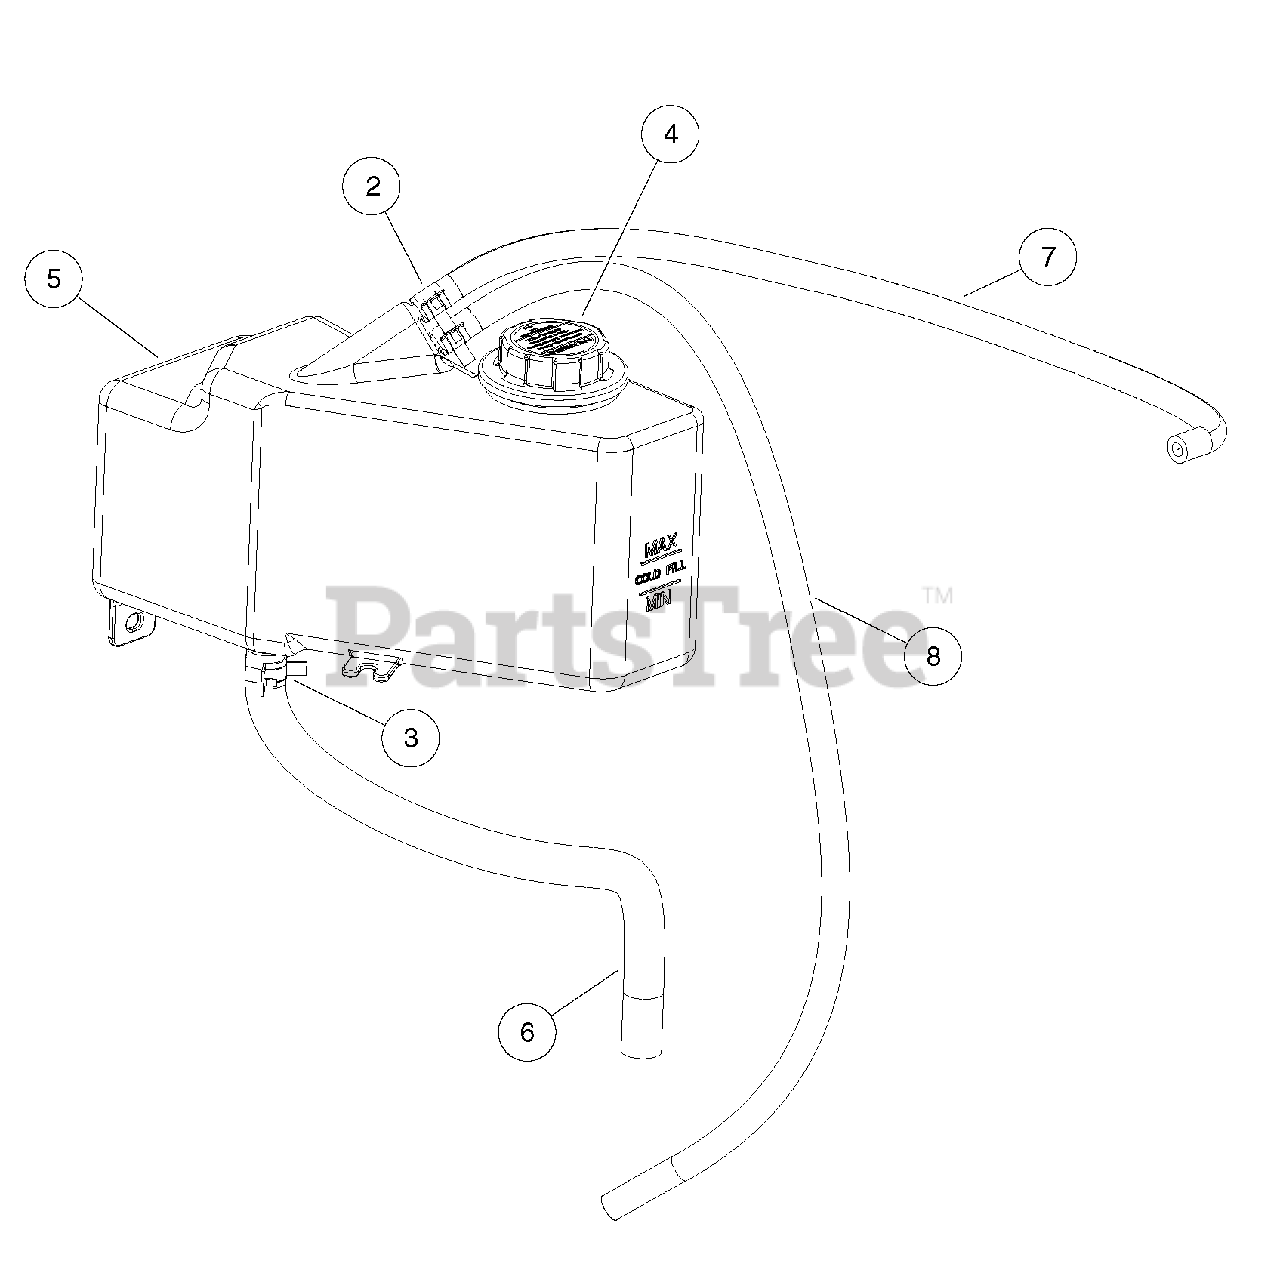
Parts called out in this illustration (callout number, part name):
1	Asm, Coolant Bottle
2	Clamp, Hose, CTB 15mm
3	Clamp, Hose, CTB 22mm
4	Cap, Radiator
5	Bottle, Coolant
6	Hose, Cut, 5/8, 445
7	Hose, Cut, Coolant, 700
8	Hose, Cut, Coolant, 1100
